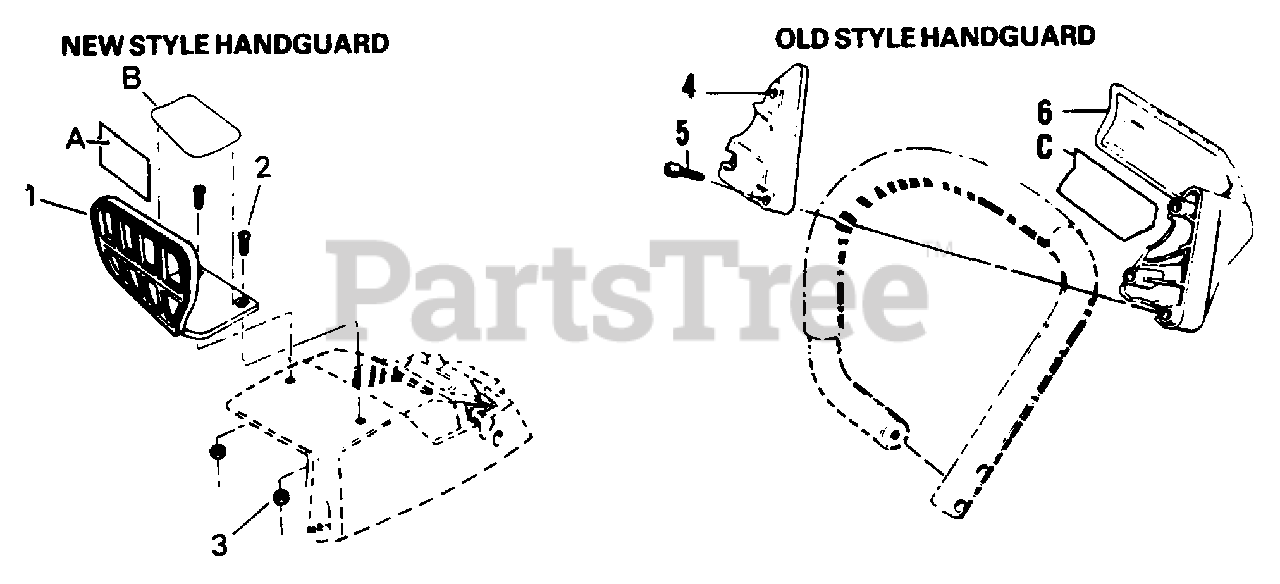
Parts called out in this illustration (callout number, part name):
1	Handguard
2	Screw-10-24 x 1/2
3	Nut - #10-24
4	Cap - Handguard
5	Screw - #10x1 - Pan Hd. - Handguard
6	Handguard
A	Decal-Kickback
A	Guide Bar Powerhead
A	Bow Guide Powerhead
B	Decal-Starting Instructions
C	Decal-Kickback Warning
C	Guide Bar Powerhead
C	Bow Guide Powerhead
